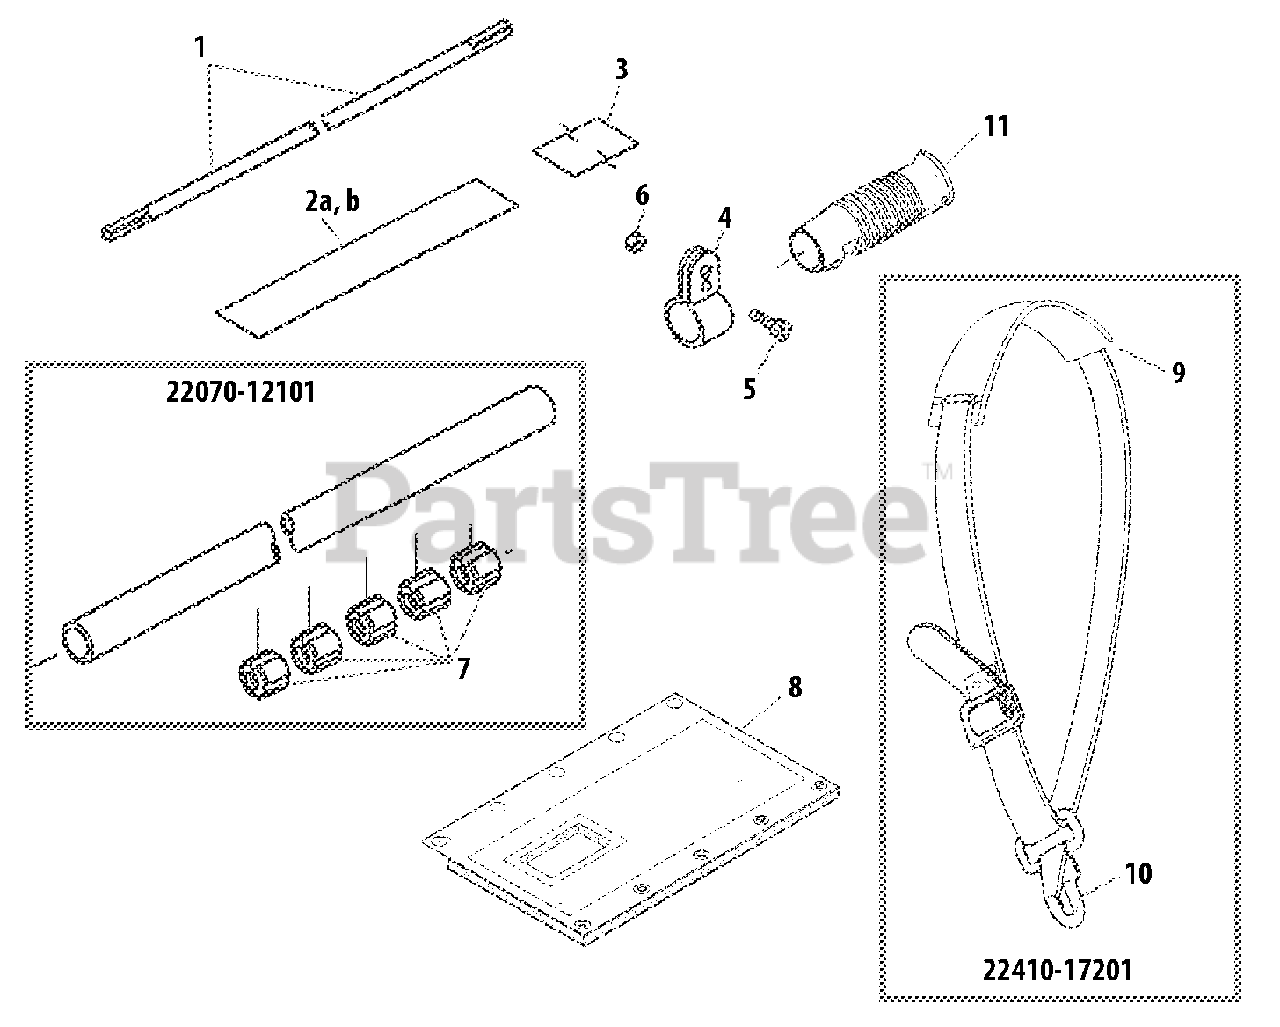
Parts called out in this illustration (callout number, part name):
1	PIPE, MAIN
2	LABEL - MODEL
3	LABEL - CAUTION
4	BRACKET
5	SCREW - 5X12
7	BUSHING
8	SLEEVE, PROTECTOR
9	PROTECTOR
10	HOOK
11	GRIP - REAR
22070-12101	MAIN PIPE ASSY
22410-17201	STRAP ASSY
